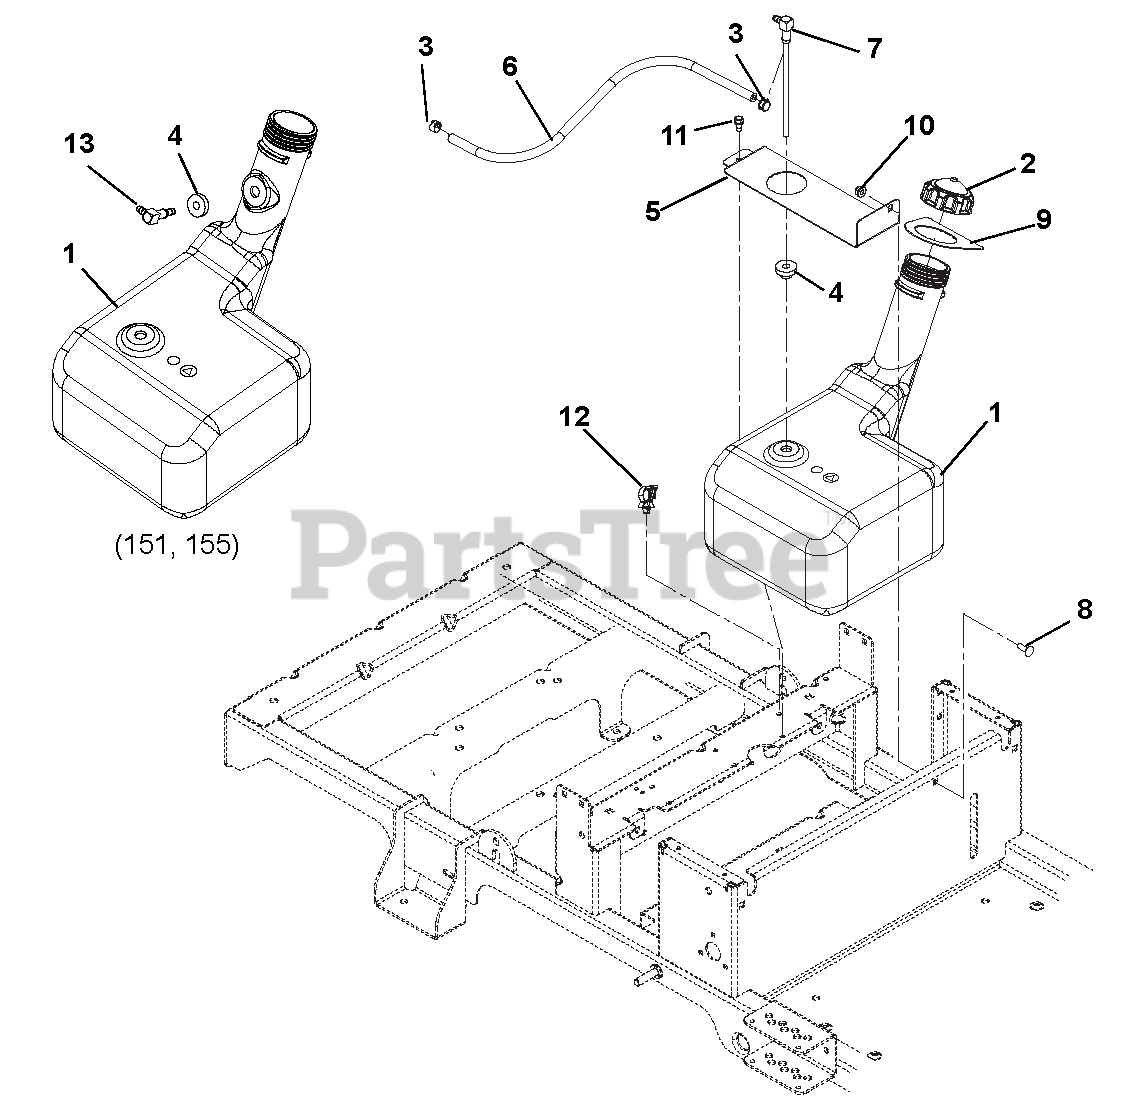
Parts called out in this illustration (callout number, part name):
1	FUEL TANK
1	FUEL TANK 2.5G W/VENT PORT
2	FUEL CAP
2	FUEL CAP, 225 CARB W/12" THTR
3	CLAMP, FUEL LINE
4	BSHG-FLG .375 X 1.062 X .625 R
5	BRKT, TANK STRAP
6	HOSE, .25 LOW-PERM BULK GAS
7	ASSY-PICK-UP, FUEL 6.5L
8	@BLT-RDHDSQNK .25-20X.75 G5YZ
9	SEAL-TANK NECK
10	@NUT-LK-NYL-FLG .25-20 YWZC
11	SCR-TAP .25-20X.50 HWH TR YWZ
12	WIRE CLIP
13	FITTING, 90 DEGREE .25" FUEL
